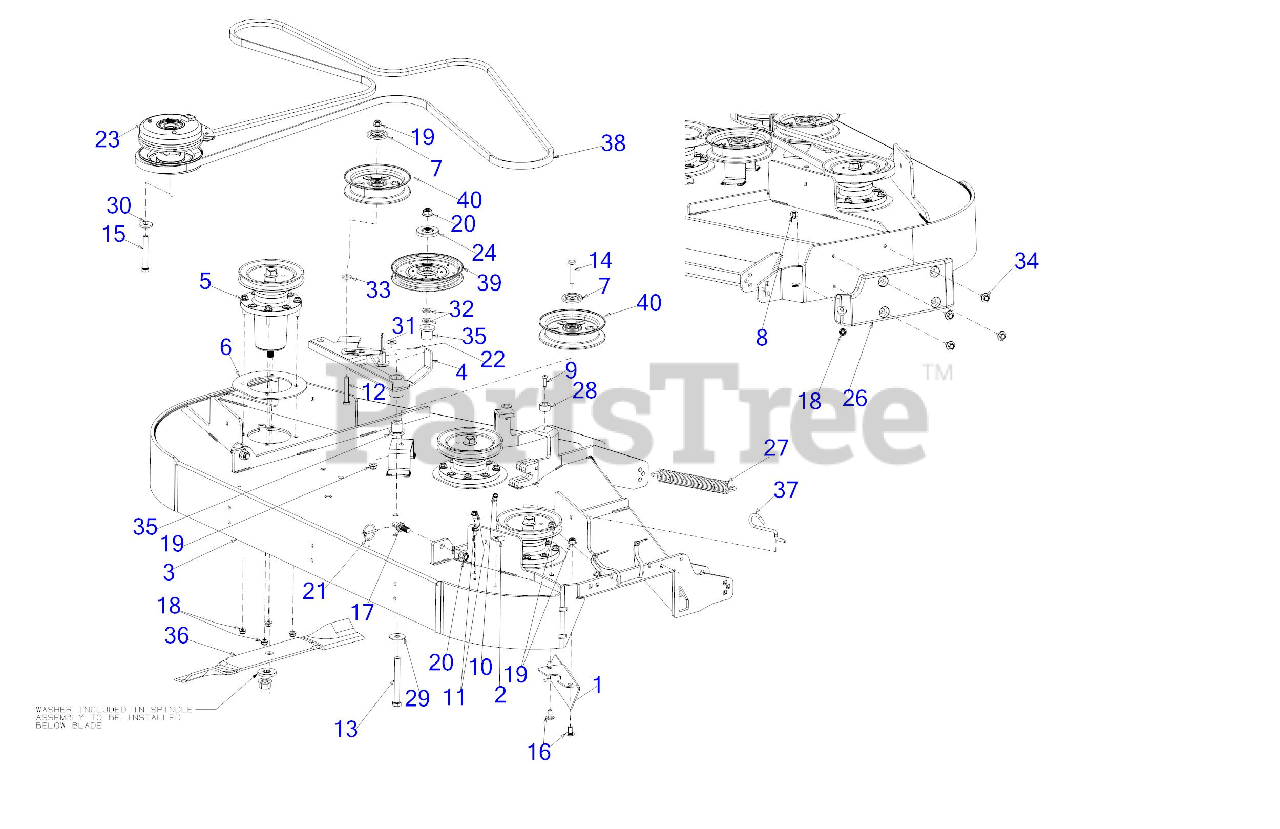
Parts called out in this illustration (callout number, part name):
2	HOOK RETAINER BRACKET
4	DECK IDLER ASSEMBLY
5	SPINDLE ASSEMBLY
5	Cub Cadet 60" SPINDLE ASSEMBLY (07386)
7	PULLEY CAP 1.875 DIA
8	CARRIAGE BOLT 5/16-18 x 1.00
9	SCREW 1/4-20 x 1.0
10	SCREW 1/4-20 X.500
11	SCREW 5/16-18 x .500
12	HEX SCREW-3/8-16X2.5 GR5
13	SCREW 1/2-13 x 4.5 GR 5
14	SCREW 3/8-16 x 2.0 GR5
15	SCREW 7/16-20 x 3.25 GR5
16	CARRIAGE BOLT 3/8-16 x .75
18	FLANGE LOCK NUT 5/16-18
22	COTTER PIN 3/32
23	ELECTRIC PTO CLUTCH
24	PULLEY CAP 1/2"
26	DECK SKID PLATE (LH)
27	EXTENSION SPRING
29	WASHER .51 x 1.5 x .07
30	FLAT WASHER .445 x 1.248 x .170
31	FLAT WASHER
32	FLAT WASHER
33	FLAT WASHER
34	SHOULDER SCREW .43X.29X5/16-18 TT
35	SHOULDER SPACER
36	21" BLADE (HI LIFT)
36	Cub Cadet 60" BLADE SET
36	Genuine Factory Parts 60" BLADE SET
36	LOW-LIFT 21"BLADE (60"DECK)
36	BLADE-HI LIFT 21.0
36	BLADE-21"MULCH 60"
36	21" XTREME BLADE
37	DECK SPRING HOOK
38	DECK BELT B x 161.75
38	Cub Cadet DECK BELT (B x 161.75)
39	IDLER PULLEY 6.0" DIA
40	5" FLAT IDLER PULLEY
